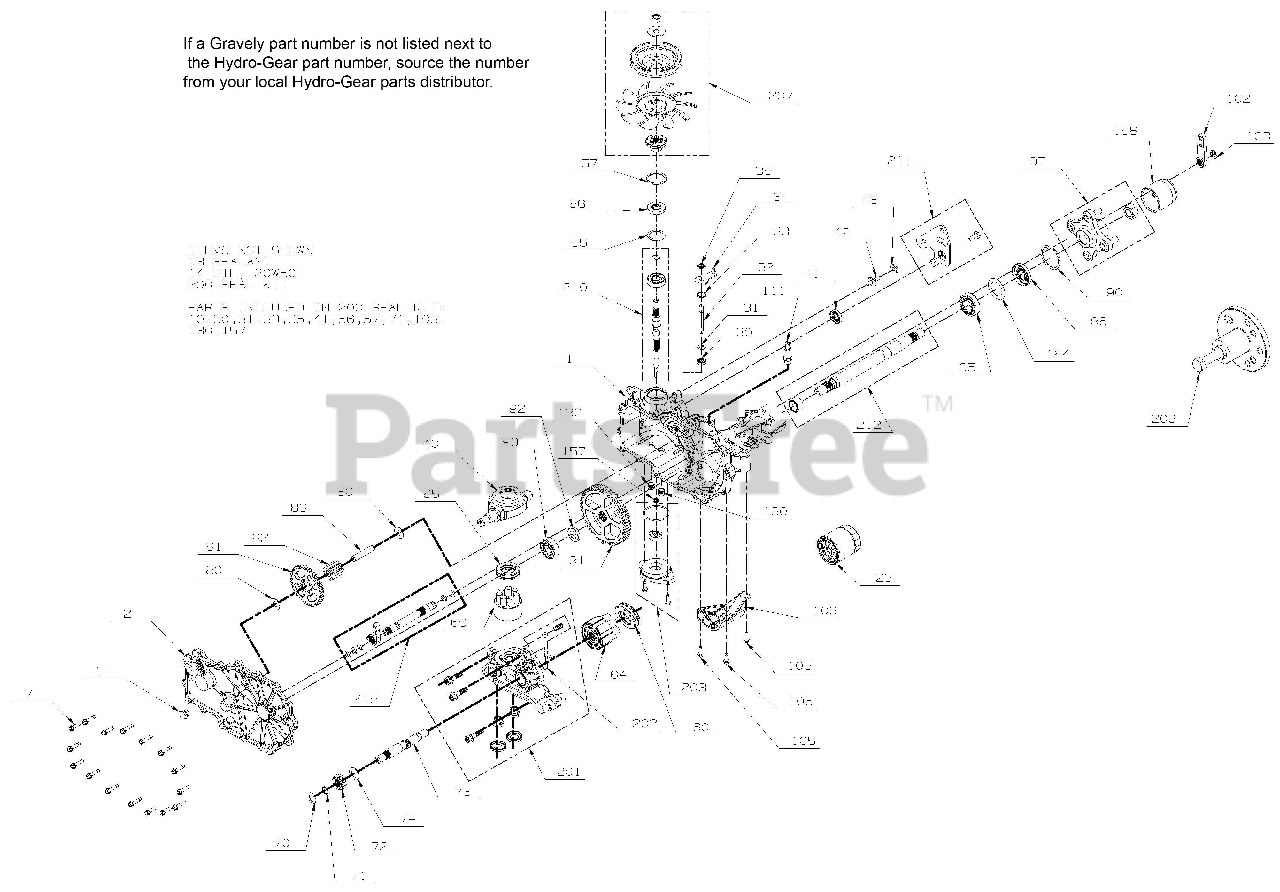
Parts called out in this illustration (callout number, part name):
1	KIT, MAIN HOUSING CHARGE, CONTROL
2	KIT, COVER SIDE
7	SCREW,HEX WASHER 1/4-20X1.125
13	SEALANT TUBE 10.1OZ.
23	OIL FILTER, TRANSMISSION
30	SEAL, LIP .375X.75X.25
31	RING. RETAINING
33	RING, RET .750
34	ARM, BYPASS
35	RING, RTNG .
40	TRUNNION, SWASHPLATE
41	SEAL, LIP 18X32X7
42	STUD. SHORT 5/16-24
48	SPACER
55	WASHER 1.23X1.56X.04
56	SEAL, LIP 17X40X7
57	RING, RET 1.56 INT
60	HG THRUST BEARING (51462)
64	HG 16CC CYLINDER BLOCK (71579)
65	BEARING. THRUST 30 X 52 X 13
69	ASSY, BLOCK 7 PISTON
70	WASHER .63X1.0X.05
71	RING, RET 62 EXT
73	SHAFT, MOTOR
74	WASHER .71 X 1.16 X .04
80	WASHER .5X1.0X.032
83	JACK SHAFT (PIN)
90	RING, RETAINING
93	KIT, BEARING
95	BEARING, BALL 25.4 X 52 X 15
96	SEAL, LIP
97	KIT, HUB 4 BOLT
102	HANDLE, ACTUATING
105	HFHCS 1/4-20X.75
106	GUARD, FILTER, RH
111	KIT, FITTING 1/2 BEADED 9/16
130	TUBE, CHARGE TRIPLE O-RING
157	KIT, GEROTOR SEAL
158	CAP, AXLE
164	WASHER, 1.355 x 2.035 x .021 FLAT
200	KIT, SEAL
201	KIT, CENTER SECTION CHARGE
202	KIT, CHARGE RELIEF
203	KIT, CHARGE
207	FAN PULLEY KIT 4.5X1.625
209	HUB PULLER 4 BLT HYDGEAR 71459
210	INPUT SHAFT 2800 HYDGEAR 71442
211	KIT, ARM, CONTROL
212	KIT, SHAFT AXLE
215	KIT, INBOARD, ROT A / LH ROT B
